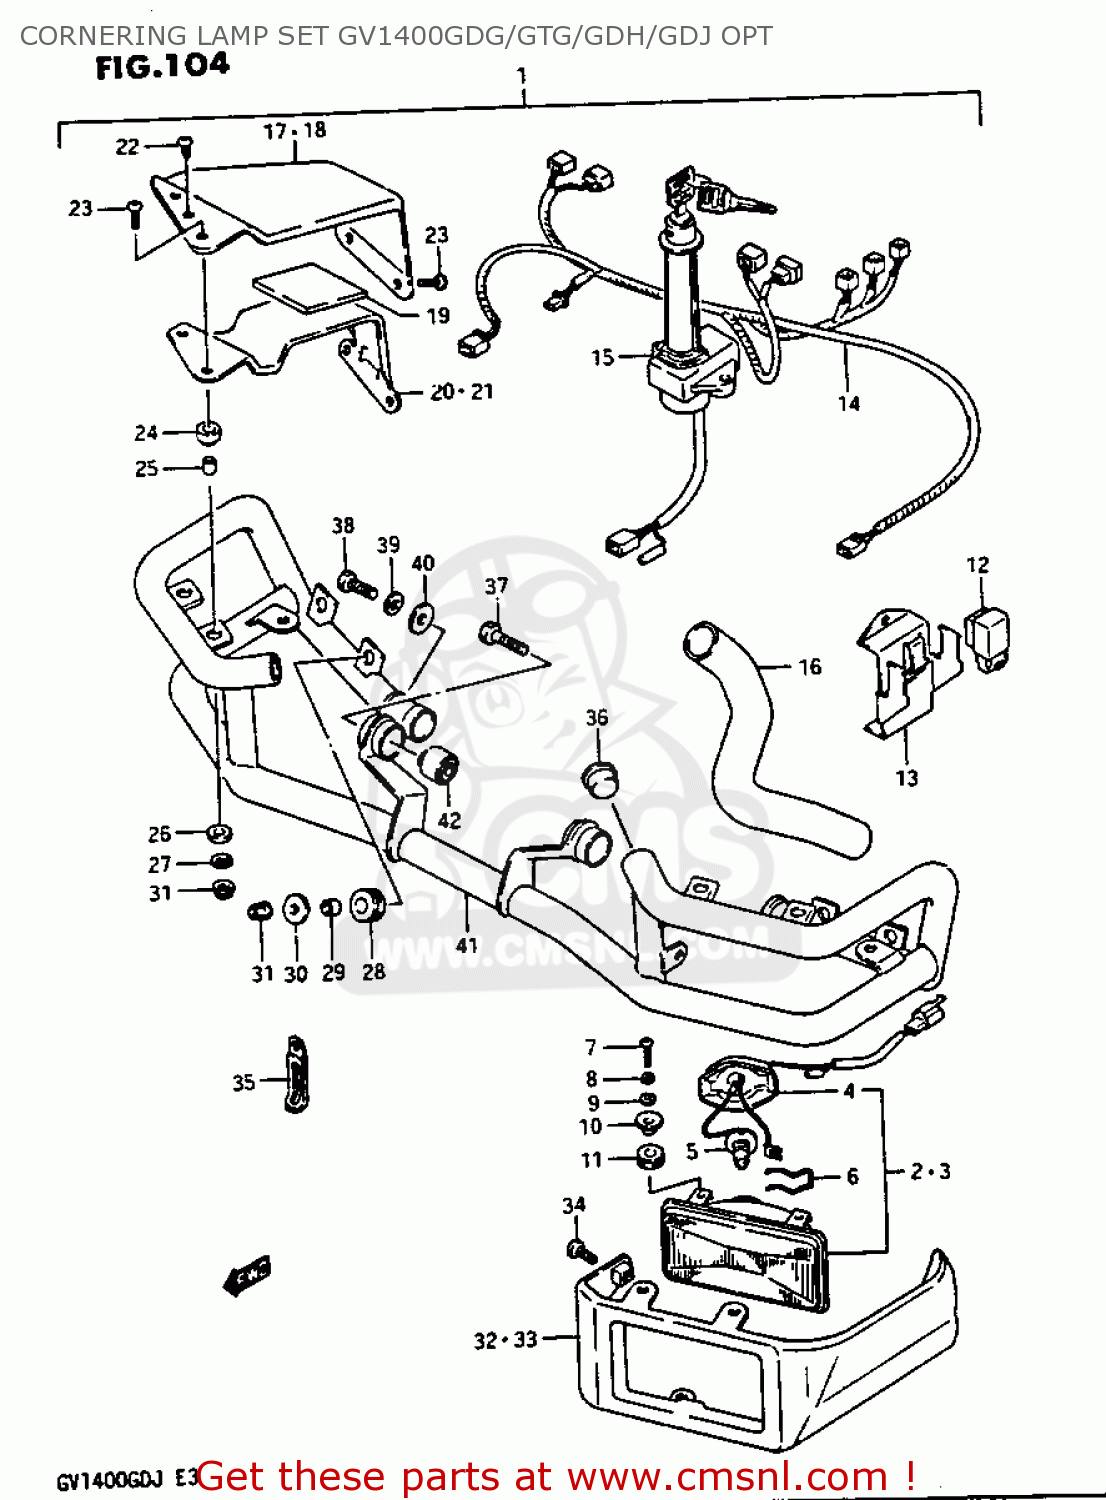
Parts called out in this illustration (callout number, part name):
1	LAMP SET,CORNERING
2	LAMP ASSEMBLY,CORNERING,RIGHT
3	LAMP ASSEMBLY,CORNERING,LEFT
4	SOCKET
5	BULB 12V 35W H3
6	SPRING
7	SCREW
8	LOCK WASHER
9	WASHER
10	SPACER(4.2X8X9)
11	CUSHION
12	RELAY,NEUTRAL STARTER
13	BRACKET, RELAY
14	WIRE COMP,CORNERING LAMP
15	SWITCH ASSEMBLY,IGNITION
16	HOSE,RADIATOR OUTLET
17	COVER,CORNER LAMP,RIGHT
18	COVER,CORNER LAMP,LEFT
19	CUSHION,CORNER LAMP CVR CTR
20	COVER,CORNER LAMP,LOWER
21	COVER,CORNER LAMP,LOWER
22	SCREW
23	SCREW
24	CUSHION
25	SPACER
26	CUSHION
27	WASHER (5.5X14X1.2)
28	CUSHION
29	SPACER(6.1X9X7.5)
30	WASHER (5.5X20X1.2)
31	NUT
32	COVER COMP,ACCESSORY B
33	COVER COMP,ACCESSORY B
34	CLAMP
35	CLAMP
36	CAP,ACCESSORY BAR
37	BOLT
38	BOLT
39	WASHER
40	WASHER (8.2X24X1.6)
41	BAR SET,ACCESSORY
42	BUSH
